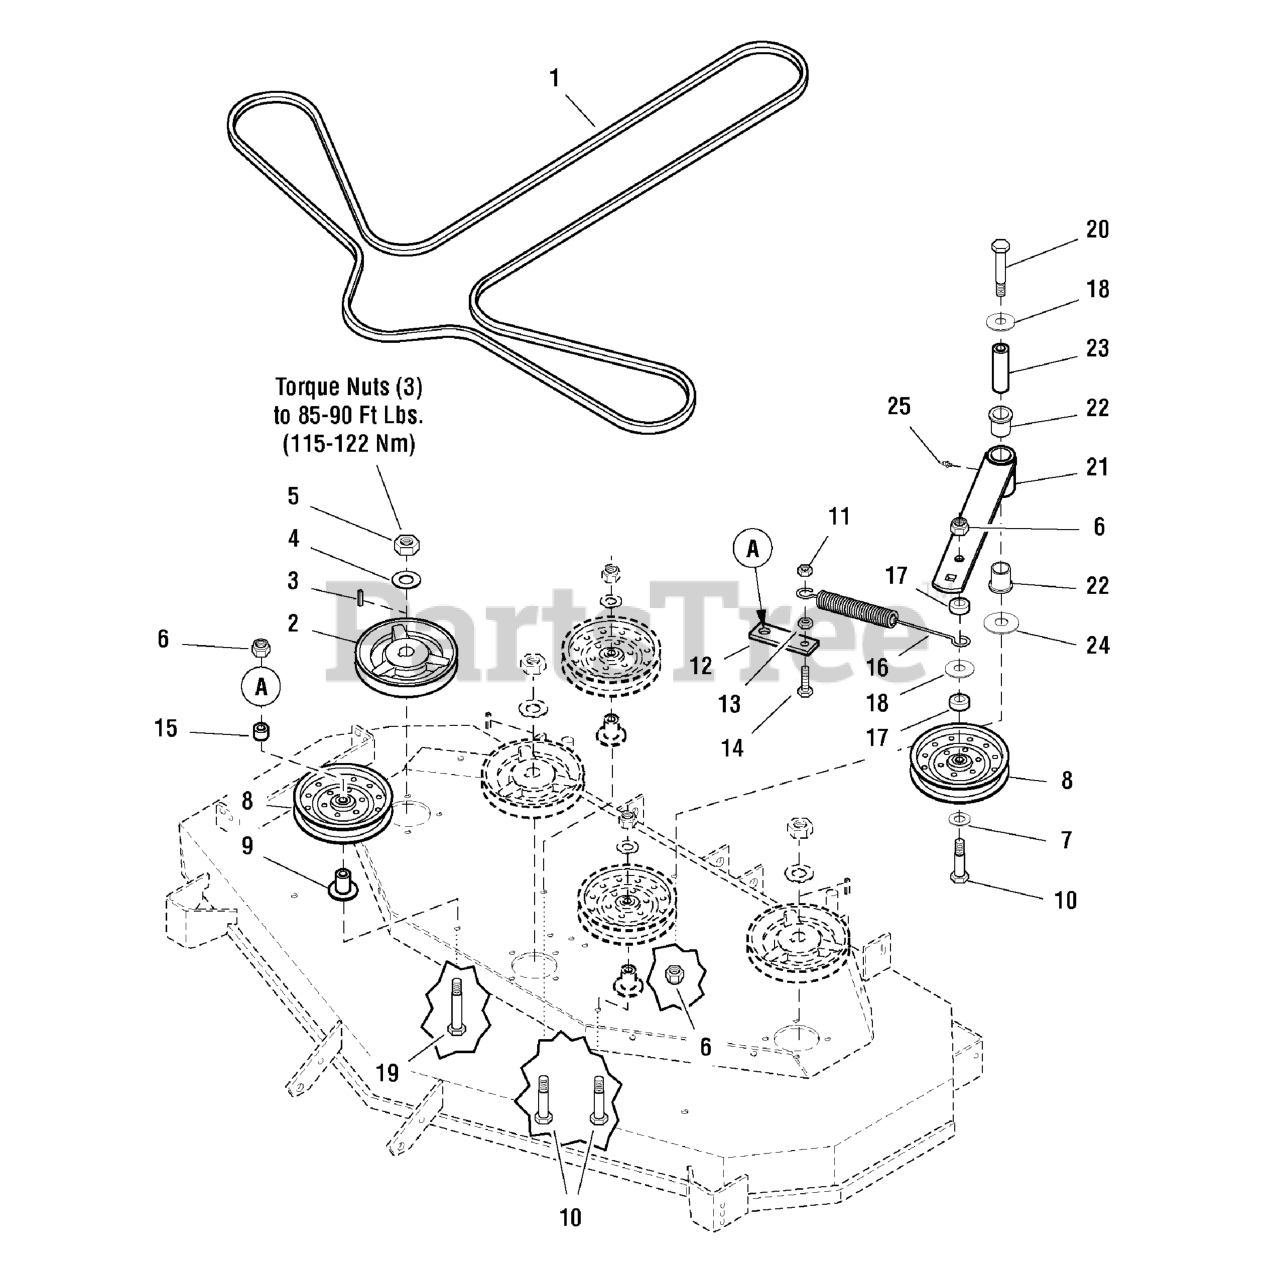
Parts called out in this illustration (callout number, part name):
1	BELT, 5V, 173.00"EL, LRG ARAMID, WRPD,RC
2	SPINDLE PULLEY
3	KEY, 1/4 SQ. X 1-1/4
4	WASHER, 3/4 BELLEVILLE
5	NUT, 3/4-16 Hex
6	NUT, 1/2-13 HEX NYLON LOCK
7	WASHER, 1/2 SAE
9	IDLER MOUNT
10	BOLT, 1/2-13 X 3" GD5 CZ
11	NUT, 3/8-16 Hex Top Lock
12	MOUNT, Idler Spring
13	NUT, 3/8-16 Hex
14	BOLT, 3/8-16 X 1-1/4" GD5 CZ
15	SPACER, .52 x 1.00 x .44
16	SPRING, Extension, Swivel End
17	SPACER, .52 x 1.00 x .44
18	WASHER, 1/2" USS
19	BOLT, 1/2-13 X 3-1/2, HEX HD, GD5, CZ (SV)
20	BOLT, 1/2-13 x 4-1/2
21	IDLER ARM
22	BUSHING, FLANGE
23	SPACER, .52 x 1.00 x 3.50
24	WASHER, 5/8" SAE
25	GREASE FITTING
